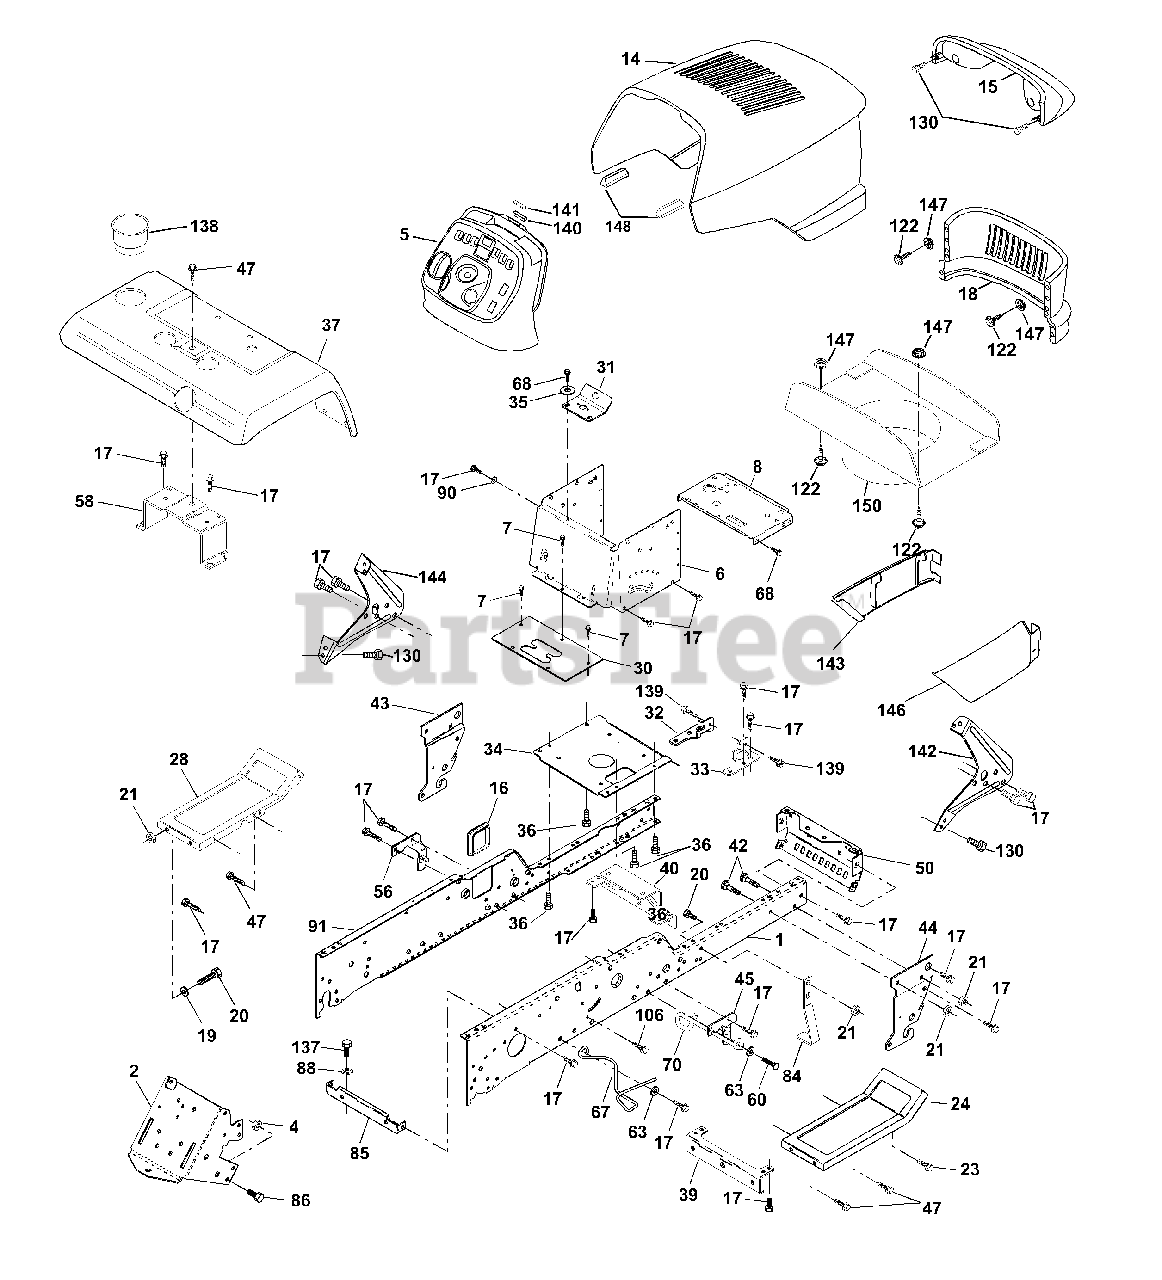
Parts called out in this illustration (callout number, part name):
1	Rail, Frame RH
2	Drawbar, Gt
4	Nut, Crownlock 7/16-14Unc
5	Dash
6	Dash Asm., Lower
7	Screw, Thd Cut 1/4-20 x 1/2
8	Support, Battery
14	Hood Asm., Pnt
15	Lens, Asm Headlight bar
16	Cover, Access
17	Screw, 3/8-16 x 3/4
18	Grille
19	Washer 13/32 x 13/16 x 12 Ga.
20	Bolt, Fin Hex 3/8-16 x 1
21	Nut, Crownlock 3/8-16 Unc
23	Screw 3/8-16 x 1
24	Footrest, RH
28	Footrest, LH
30	Saddle
31	Bracket, Supt 1-pc VGT Steering
32	Bracket, Pivot Chassis LH
33	Bracket, Pivot Chassis RH
34	Plate Asm Engine Chassis
35	Washer 11/32 x 11/16 x 16 Ga.
36	Screw 5/16-18 x 3/4
39	Bracket, Axle Front
42	Bolt, Carriage 3/8-16 x 1
43	Bracket, Spnsn Front Lh
44	Bracket, Spnsn Front Rh
45	Bracket Asm., Susp Chassis Rh
47	Screw Thdrol 3/8-16 x 1/2 TYT
50	Bracket, Chassis Front
56	Bracket Asm., Susp Chassis Lh
58	Bracket Asm., Fender
60	Screw Thdrol 3/8-16 x 1-1/4
63	Washer 13/32 x 1 x 14 Ga.
67	Guide Belt Gear Dr.
68	Screw, Thd 5/16-18 x 1/2
70	Guide, Belt Mid Span
84	Stop, Over Center Mower
85	Bracket Support Transaxle
86	Bolt, Fin Hex 7/16-14 Unc x 1
88	Washer Lock Hvy HLCL Spr. 7/16
90	Washer, Lock External Tooth 3/8
91	Rail, Frame Lh
106	Bolt 5/16-18 Type TT
122	Screw Hex Wshd 8-18 x 7/8
130	Screw HWHD Hi-Lo #13-16 x 3/4
137	Bolt Fin Hex 7/16-14 x 1 Gr. 5
138	Cupholder YTGT
139	Bolt Shoulder 5/16-18 TT
140	Magnet YTGT
141	Stricker Plate YTGT
142	Bracket Dash RH
143	Grille Skirt RH
144	Bracket Dash LH
146	Grille Skirt LH
147	Fastener Nutpal
148	Extrusion Bumper
150	Duct Heat Hood
